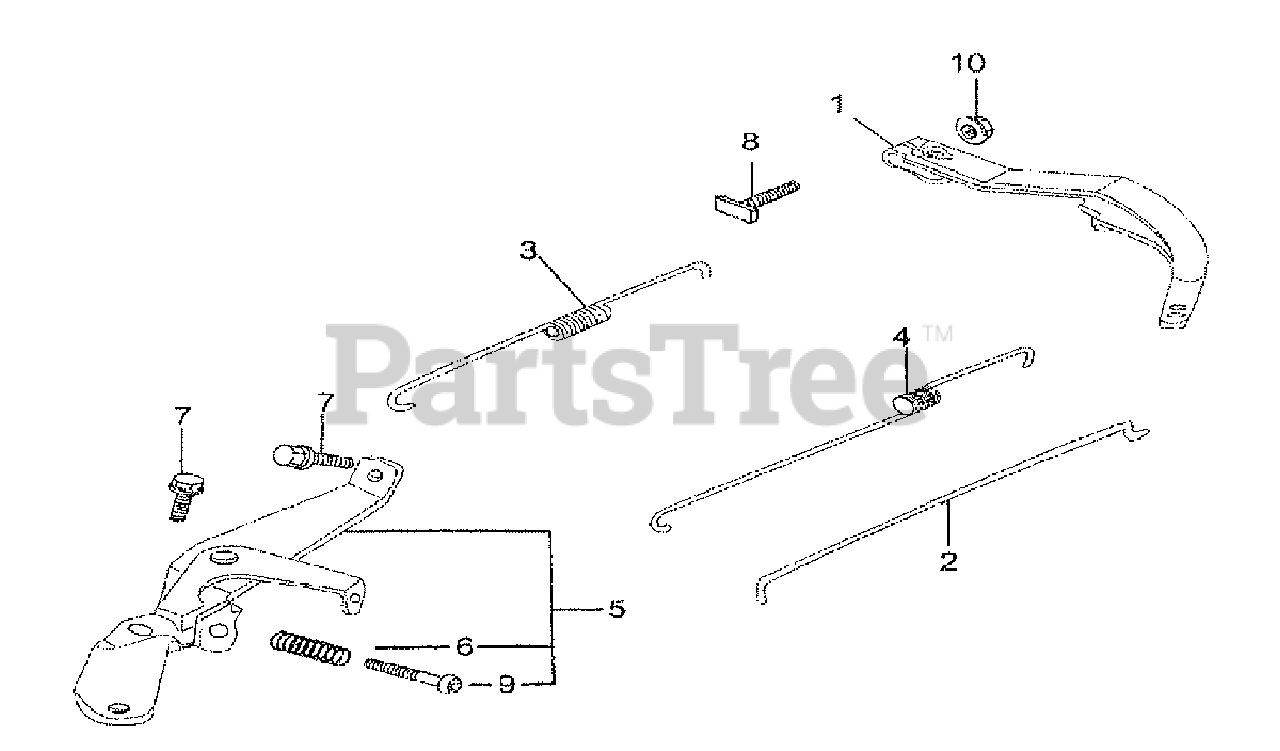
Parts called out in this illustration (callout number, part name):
2	ROD, GOVERNOR
3	SPRING,THROTTLE RETURN
4	SPRING, CONTL, ADJ.
5	THROTTLE ARM INCLD(5,6,9)
6	SPRING, GOVERNOR
7	BOLT, FLANGE 6 X 12
8	BOLT, GOV.ARM(T) 6 X 21
9	SCREW, PAN 5 X 35
10	NUT, FLANGE 6MM
